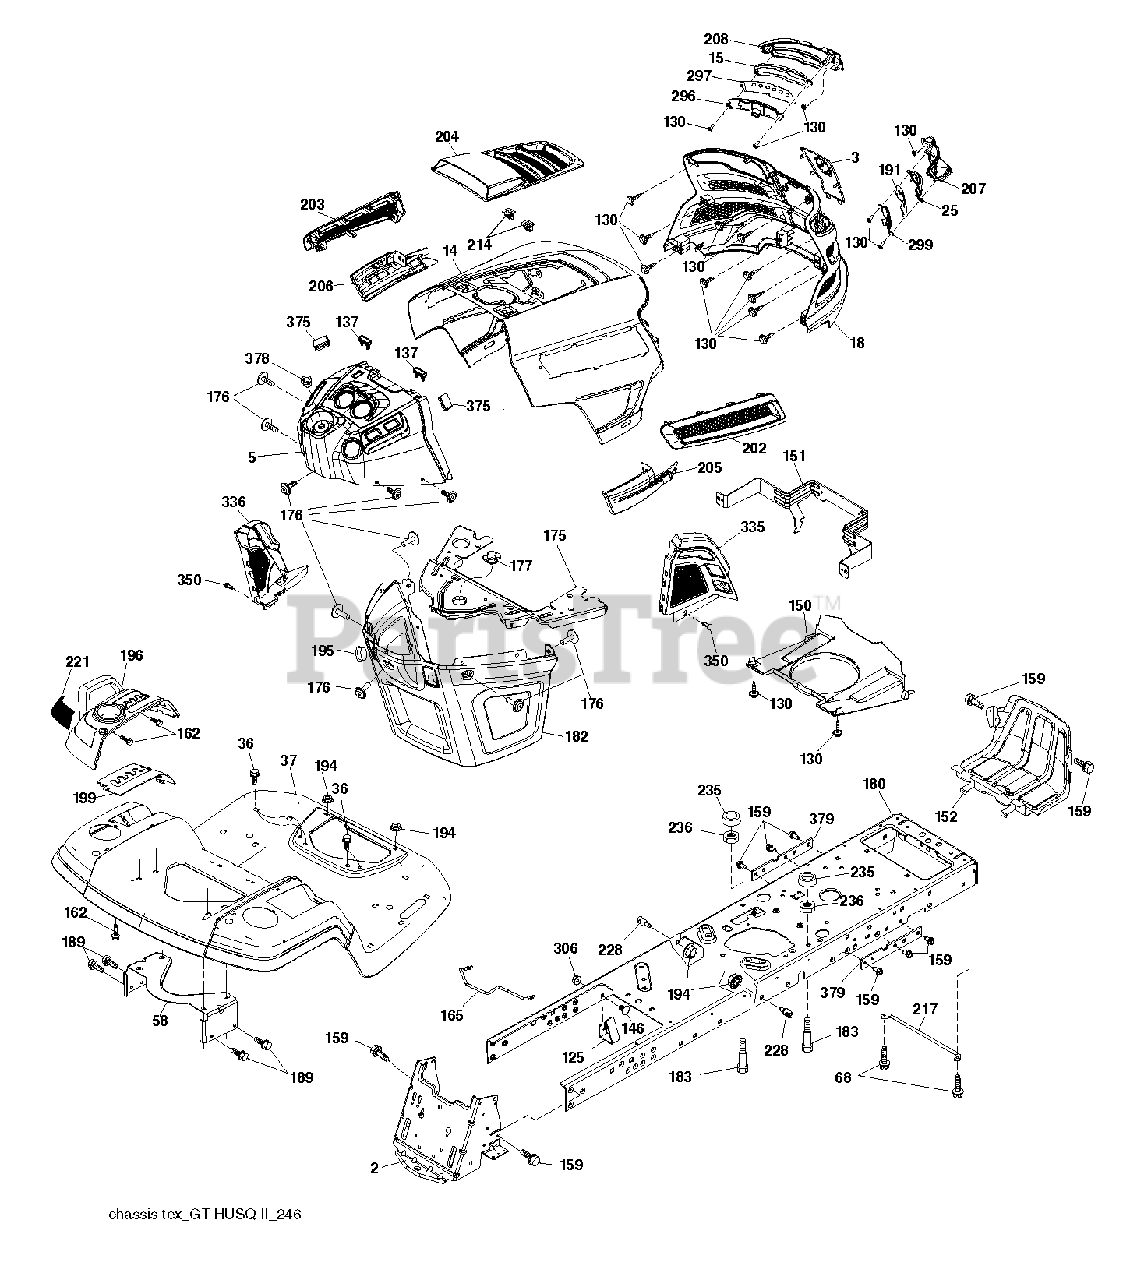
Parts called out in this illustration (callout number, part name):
2	DRAWBAR.STGT
3	APPLIQUE.SUBASM.GT.HUSQ.II
5	DASH.UPR.GT2.DUAL.RD.PT
14	HOOD.ASM.HUSQVARNA.GT.TEX.ORAN
15	LED LIGHT.LH
18	GRILLE SUBASM.GT.II.LOW.HDLGHT
25	LENS.RH
36	SCREW 5/16"
37	FENDER HUSQVARNA GT MS668 - HU
58	BRKT.SUPPORT.FNDR/TANK
68	SCR 5/16-18 X 1/2 SELFTAP ZN
125	CLIP.FUEL.LINE
130	SCREW.#10 X 0.750.BOS
137	BUMPER DASH
146	BOLT.RDHD.SHT.SQNK.3/8-16X5/8
150	AIR.DUCT.GTV.BLACK
151	BRACKET.PIVOT.HOOD.GT.HUSQ.II
152	SHIELD.BROWNING.PNT.GT.V2
159	SCREW, 3/8-16X3/4
162	SCREW.HI-LO.CONSOLE
165	SUPPORT.TANK.REAR.B/TE
175	Crossmember Plate
176	SCREW.#10-24X5/8.RN.QU
177	BUSHING STEERING
180	CHASSIS.LT/GT.BOLTED
182	DASH.LOWER.COMMON.12V.ADAPTOR
183	BOLT.5/16-18X1-1/4 FULL THD
189	SCREW
191	INSERT INFLECT.RH
194	NUT LOCK HEX FLANGE 5/16-18
195	PLUG.HOLE.DASH.LOWER.12V.BLK
196	CONSOLE.ASM.DECKLIFT.HUSQGT.DL
199	PLATE.DECK.LIFT.HUSQVARNA.GT
202	VENT.SIDE.RH.GT.HUSQ.II.
203	VENT.SIDE.LH.GT.HUSQ.II.498
204	VENT.TOP.HUSQ.GT2
205	SIDE.TRIM.RH.GT.HUSQ.II
206	SIDE.TRIM.LH.GT.HUSQ.II.GRAY
207	BEZEL GT2 LED RH W/ LOWER.ATT
208	BEZEL GT2 LED LH W/ LOWER ATT
214	CLIP.RETAINER.TINNER.
217	ROD.PIVOT.HOOD
221	REFLECTOR.LH.TEX GT HU
228	STUD.FASTNER.W/ANTI-ROTATE
235	SPACER FENDER
236	NUT.CENTERLOCK.5/16-
296	LED LIGHT.LH
297	LED LIGHT.LH
299	LED LIGHT.RH
306	NUT LOCK FLG 3/8-16 UNC
335	COVER.LOWER.DASH.RH.BLACK
336	COVER-LH.LOWER.DASH.GT2.BLACK
350	CLIP.X-MAS.TREE
375	BUMPER CLIP-ON. DASH 1"
378	BUSHING FLANGE; PLASTIC
379	CHASSIS.PLATE.REINFORCEMNT.431
